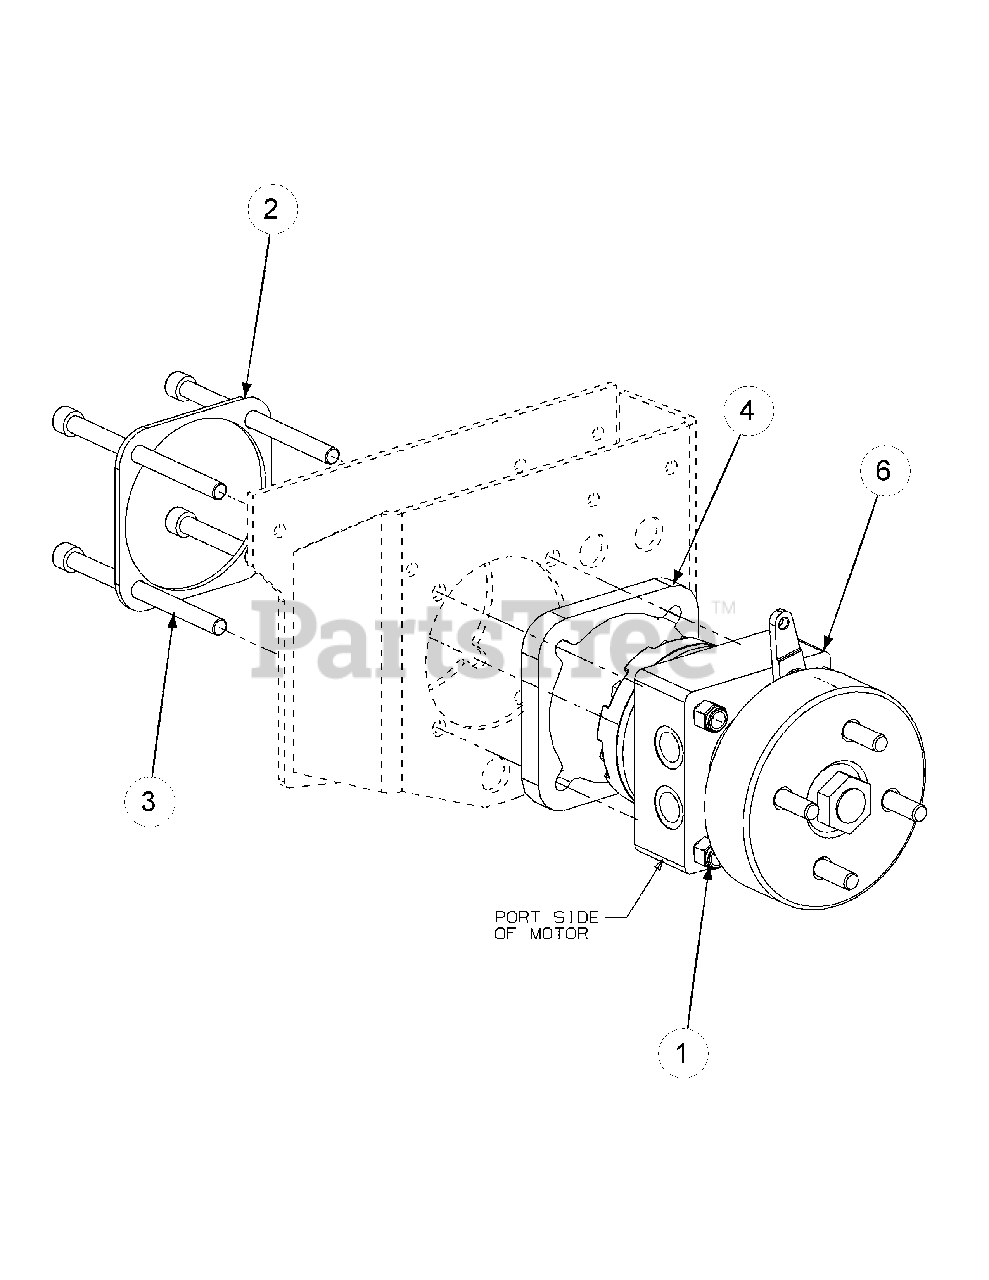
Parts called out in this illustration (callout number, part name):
1	Lock Nut, Nylon Insert, 1/2-13
2	Hydro Wheel Motor Backup Plate
3	Socket Head Capscrew, 1/2-13 x 6-1/2
4	Hydro Motor Spacer
5	Hyd. Motor, White Left Hand
6	Hyd. Motor, White Right Hand
